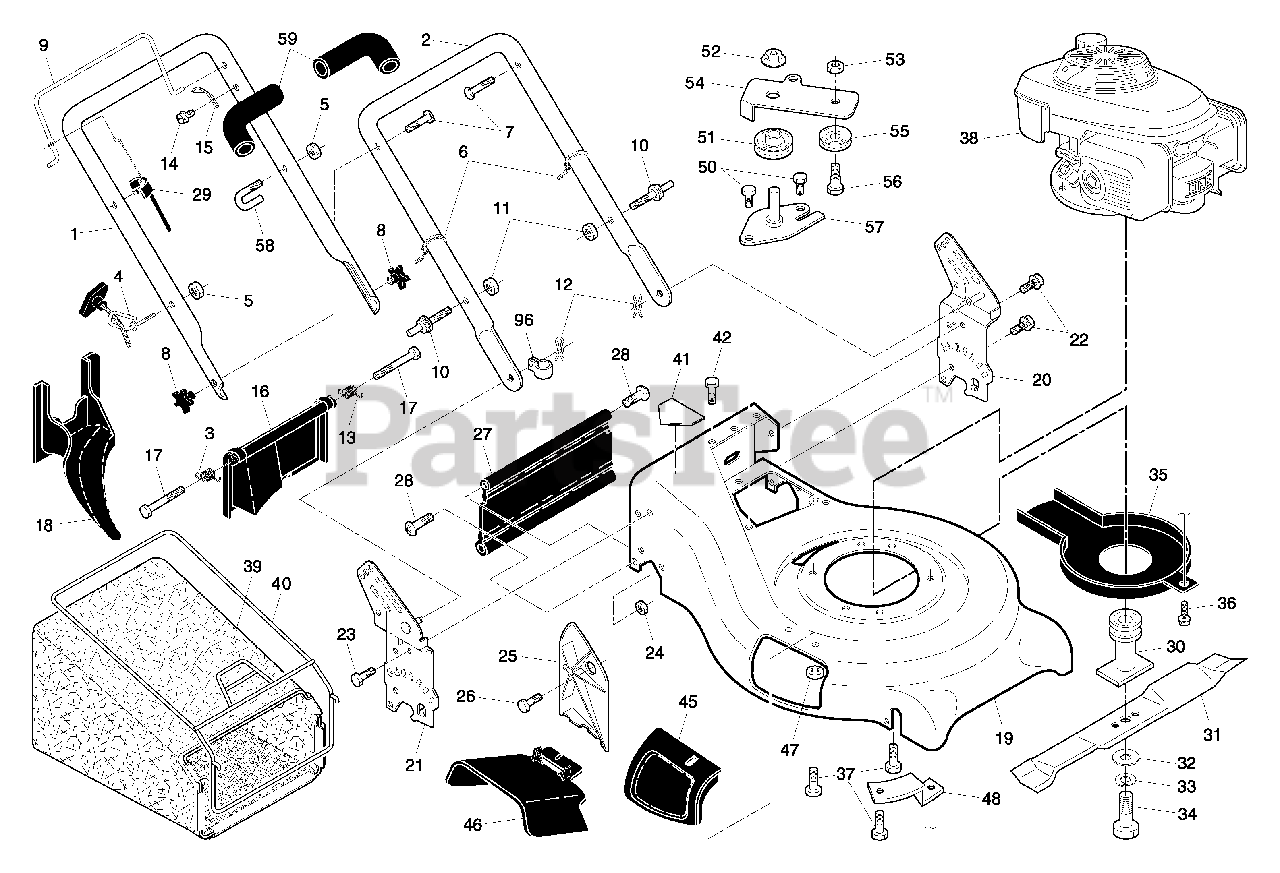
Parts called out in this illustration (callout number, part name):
1	Handle, Upper (Includes Foam Grip)
2	Handle, Lower
3	Spring, Rear Door, RH
4	Guide, Rope, Side
5	Nut, Hex Lockwasher Insert 1/4-20
6	Wire, Tie
7	Bolt, Handle 5/16-18 x 1.75
8	Knob, Handle
9	Bail, Flat, Auto-Walk, Orange
10	Bolt, Carriage
11	Nut, Hex, Centerlock 5/16-18 UNC
12	Cotter, Hairpin
13	Spring, Rear Door, LH
15	Bracket, Upstop
16	Rear Door Assembly
17	Bolt, Rear Door
18	Plug, Mulcher
19	Kit, Housing
20	Handle Bracket Assembly, LH
21	Handle Bracket Assembly, RH
22	Screw, Hex Washer Head
23	Bolt, Hex Head 5/16-18 x 5/8
24	Nut, Hex, with Lock Washer Insert 5/16-18
25	Baffle, Side
26	Screw 12 x 5/8
27	Skirt, Rear
28	Screw, Hinge 1/4-20 x 1.25
29	Engine Zone Control Cable
30	Blade Adapter / Pulley
31	Blade, 21"
32	Washer, Hardened
33	Lockwasher, Helical Spring 3/8
34	Screw, Hex Head 3/8-24 x 1.38
35	Debris Shield
36	Screw
37	Bolt, Engine
40	Frame, Grassbag
41	Danger Decal
45	Mulcher Door Assembly
46	Deflector, Discharge
48	Mounting Bracket, Debris Shield
51	Pulley Assembly
52	Nut, Hex, Flanged
53	Nut, Hex, Centerlock 5/16-18
54	Idler Arm
55	Idler Pulley
56	Shoulder Bolt 5/16-18 x 1/2
57	Bracket Assembly
59	Grip, Handle, Foam, Smooth
96	Clip, Cable
